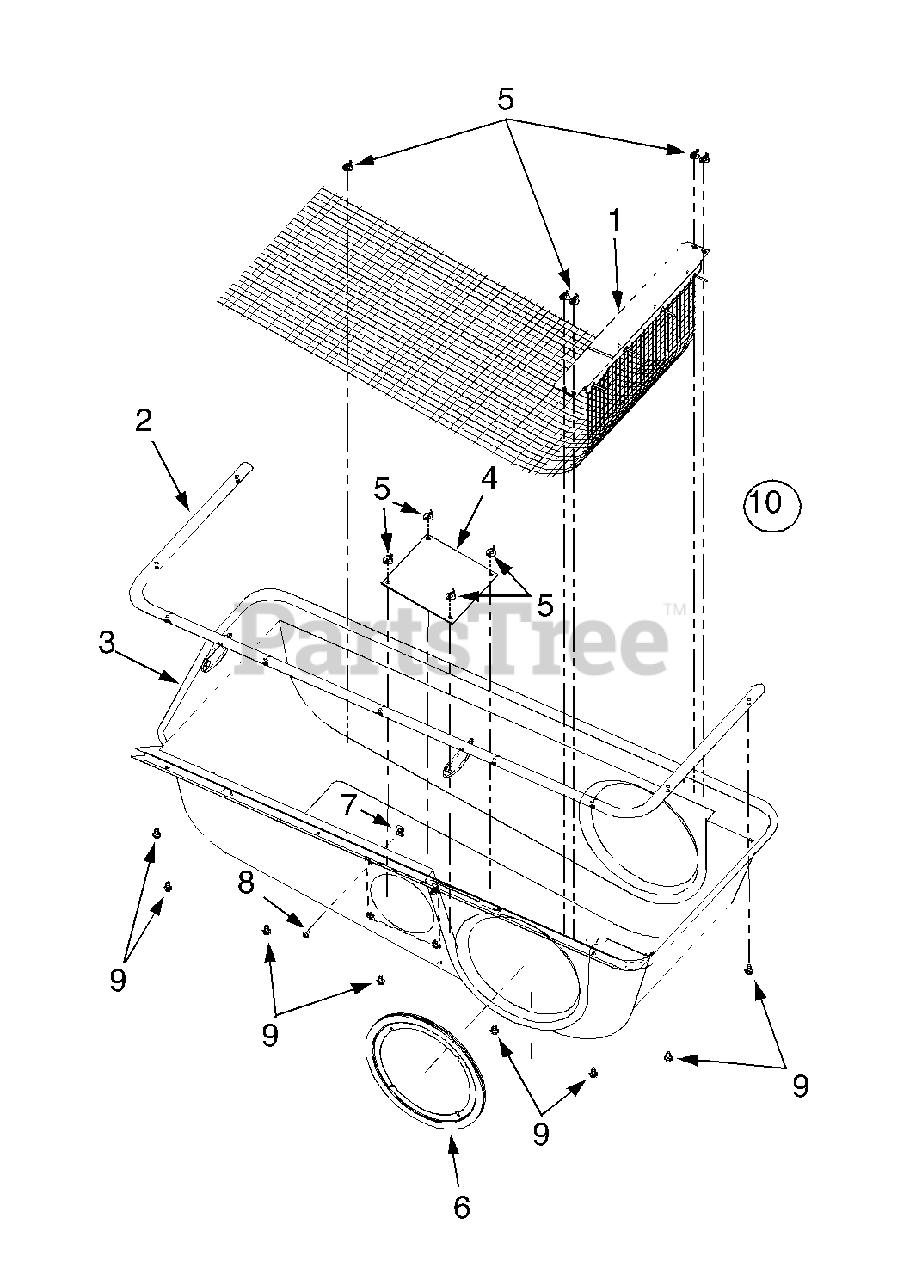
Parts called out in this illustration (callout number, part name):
3	Grass Catcher Cover
4	Plastic Plate
5	Zip Twist Fastener
6	Tube Seal
7	U-Type Speed Nut
8	Screw, #10-16 x 0.5"
9	Hex Screw, 1/4-20 x 0.5"
10	Grass Catcher Cover Assembly
